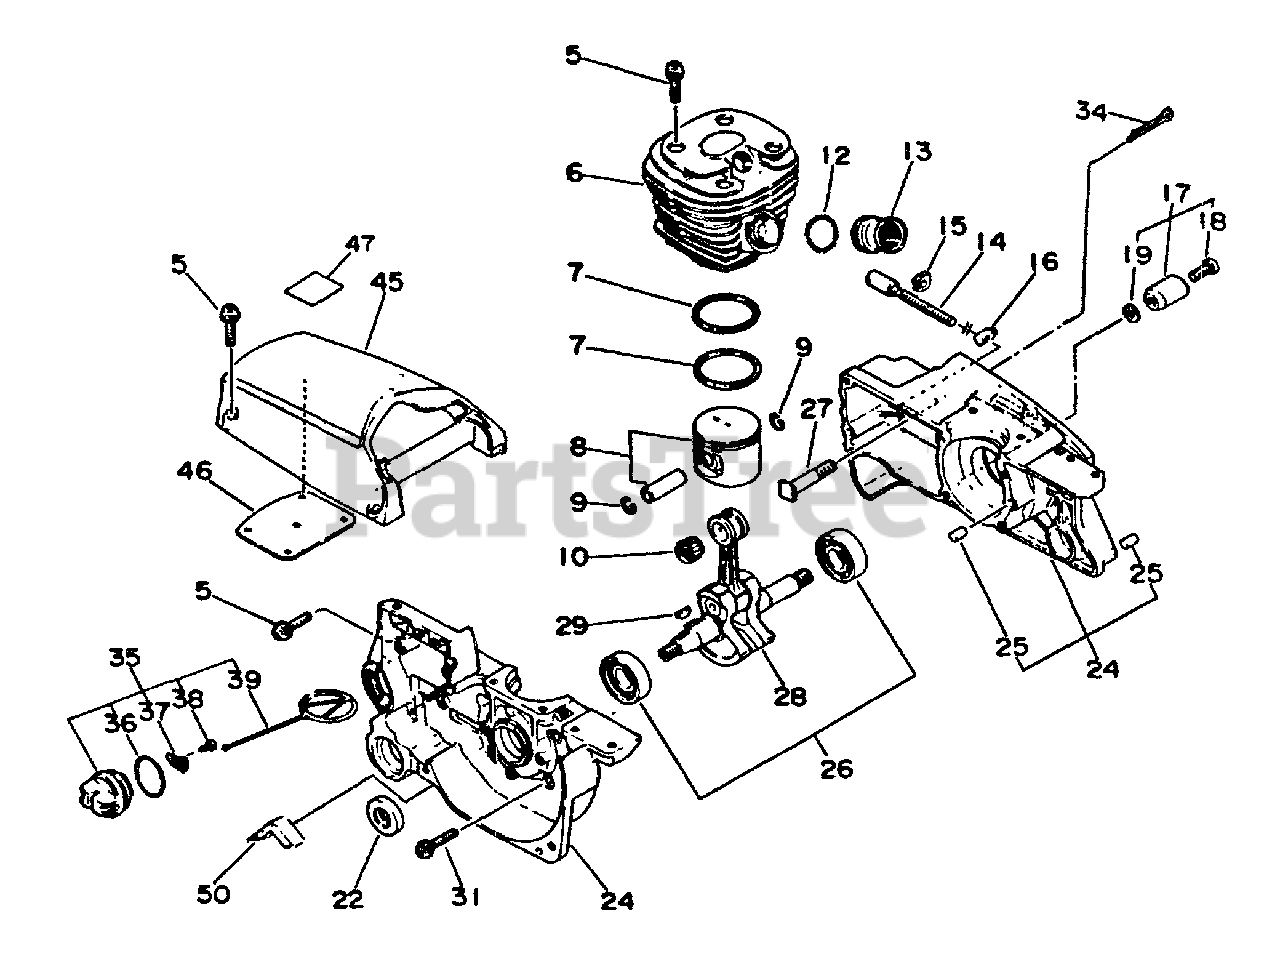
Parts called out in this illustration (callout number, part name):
5	SCREW - 5X20
6	CYLINDER
7	RING, PISTON
8	PISTON KIT
9	RING, RETAINING - 8
10	BEARING, NEEDLE - WHITE
10	BEARING, NEEDLE - BLUE
10	BEARING, NEEDLE - RED
12	BAND
13	BELLOWS, INTAKE
14	SCREW, TENSIONER
16	TENSIONER, CHAIN
17	CHAIN CATCHER KIT
18	SCREW - 5X20
19	WASHER - 5
22	SEAL, OIL
24	CRANKCASE KIT
25	PIN - LOCATING
26	BEARING SET
27	STUD, GUIDE BAR
28	CRANKSHAFT ASSY
31	SCREW - 5X30
34	PIN, SPLIT - 2X16
35	CAP ASSY
37	RETAINER
38	SCREW - 3X8
39	CONNECTOR, CAP
45	COVER, ENGINE
47	LABEL - KICK BACK
50	CUSHION
